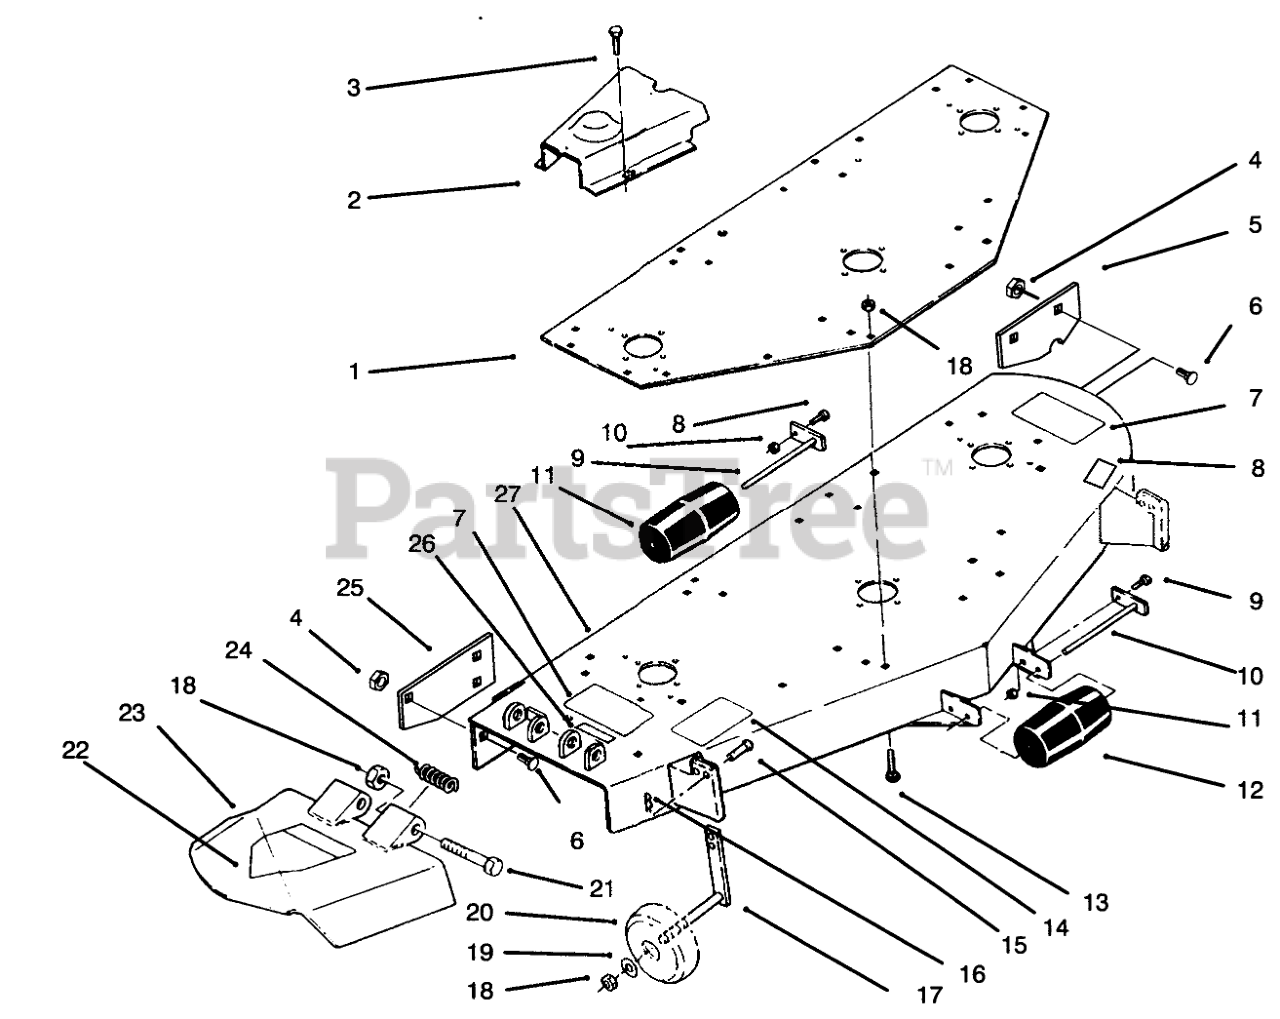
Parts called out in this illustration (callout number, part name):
1	PLATE-TOP REINFOR R
3	Belt Cover
3	SCREW-HWH, TAPTITE
4	NUT-LOCK, NI
5	PLTE WEAR LH
6	BOLT-CARR
7	DECAL-DANGER
8	DECAL - WHEEL ADJUSTMENT
9	Bolt
10	ROLLER-SHAFT
11	NUT-LOCK, NI
12	ROLLER-ANTI SCALP
13	BOLT-CARR
14	DECAL-BELT INSTALL
15	Pin-Clevis
16	PIN-HAIR
17	GAGE-WHEEL
18	NUT-LOCK, NI
19	WASHER-FLAT
20	Gage-Wheel
21	SCREW-HH
22	Chute Guard Assembly (Incl. Ref. #23)
23	DECAL-DANGER
24	SPRING
25	Wear Plate RH
26	DECAL-CAUTION
27	Deck (Incl. Ref. #7 & 26)
